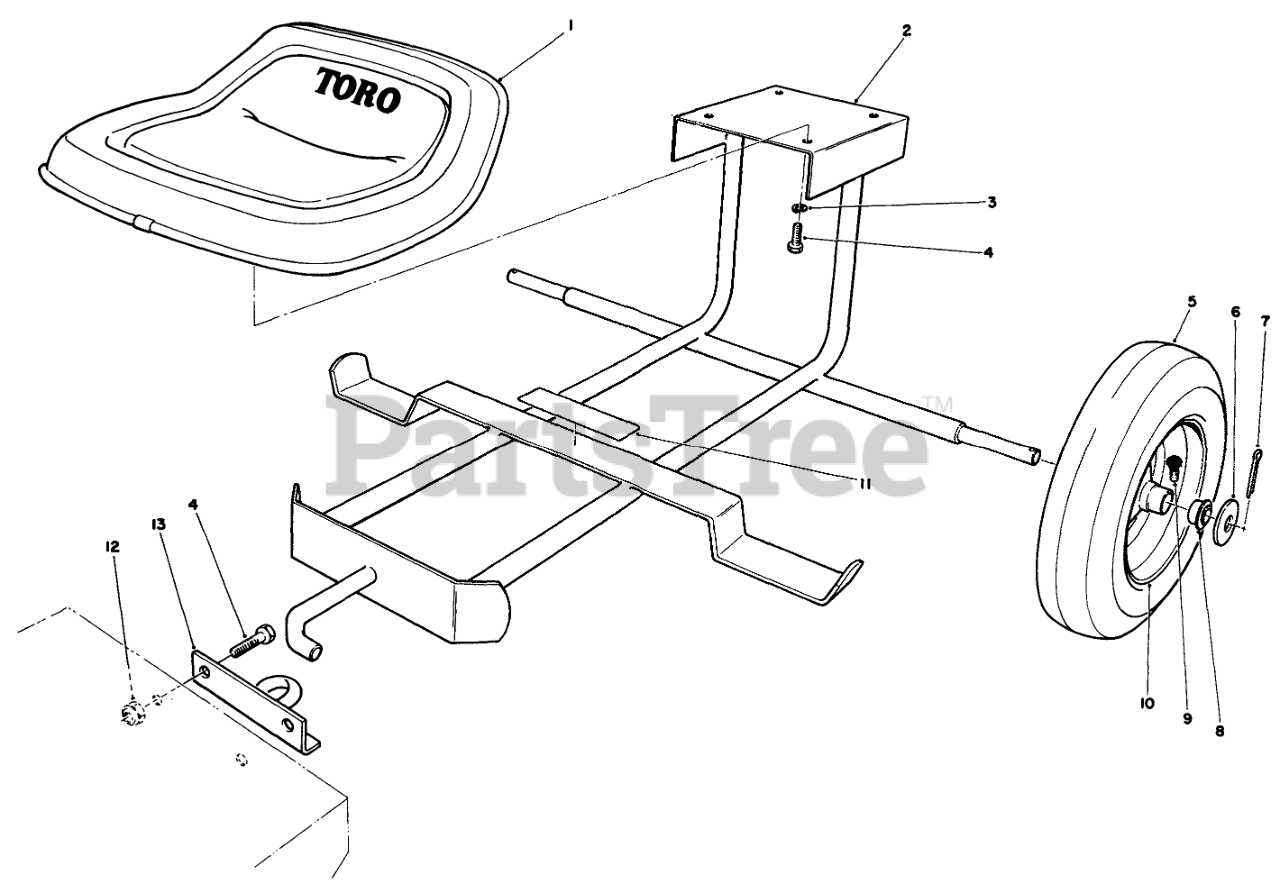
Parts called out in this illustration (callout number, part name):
2	Frame ASM
3	WASHER-LOCK
4	SCREW-HH
6	WASHER-FLAT
7	PIN-COTTER
8	BEARING
9	VALVE STEM-INNER TUBE
10	WHEEL
11	SULKY DECAL
12	NUT-LOCK, NI
13	HITCH
